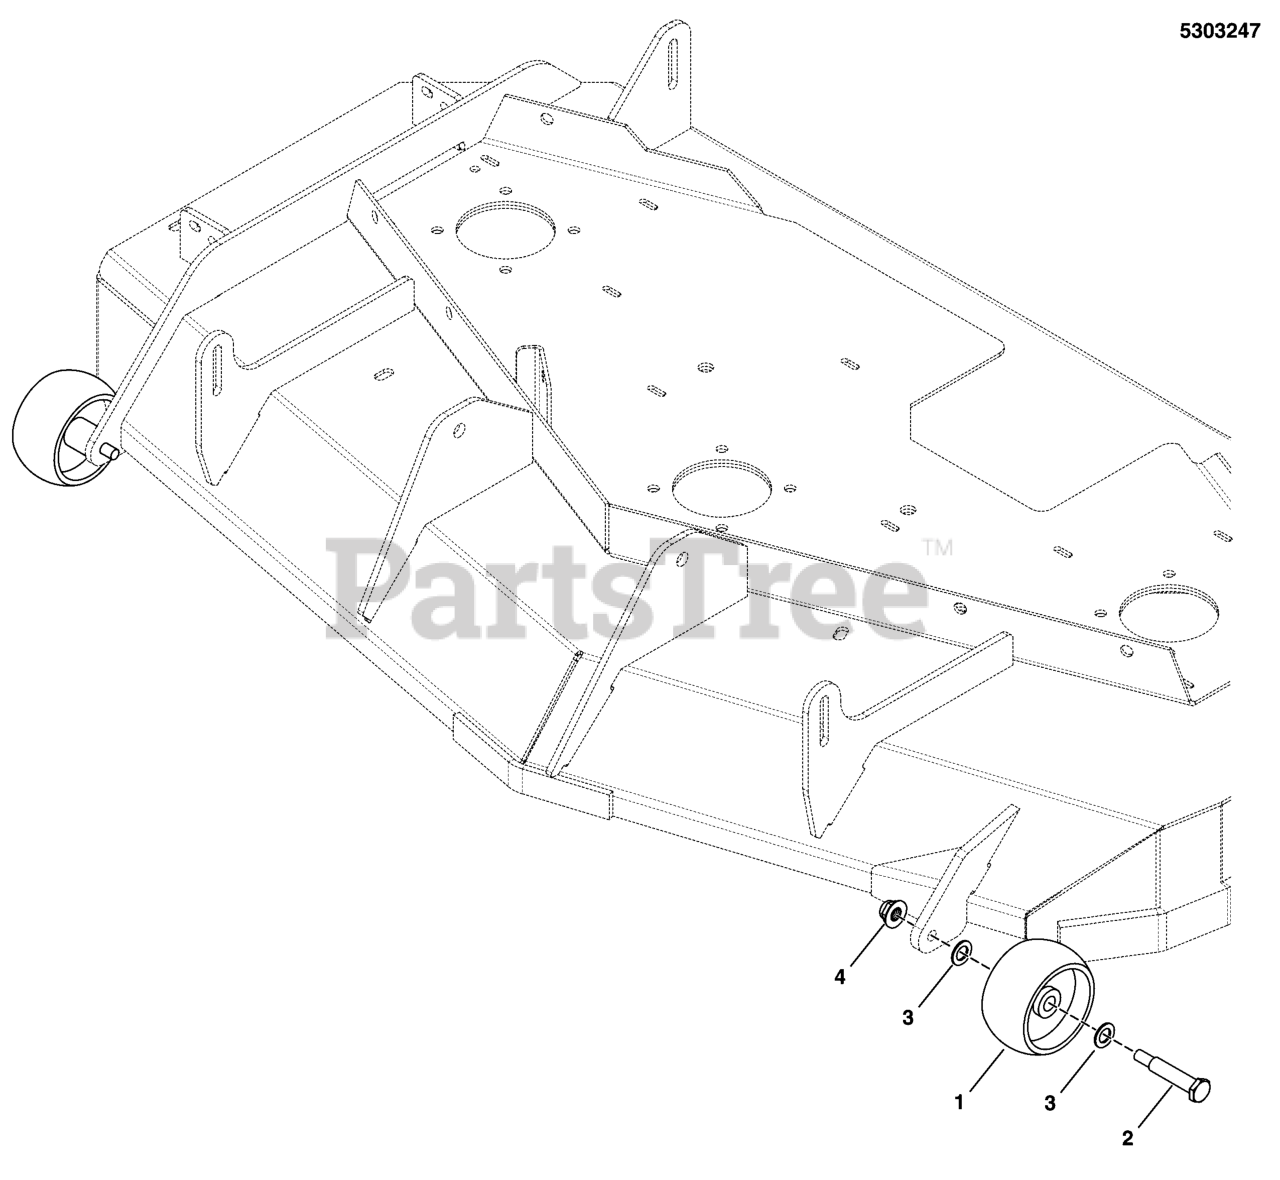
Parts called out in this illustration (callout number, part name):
1	WHEEL- 2.00 WIDE 3.88 DIA 0.531ID POLY
2	BOLT-WHEEL 3/8-16X2.781 .750 THRD
3	WASHER,.516IDX.875ODX.06,FLAT,ZC/CL
4	NUT, 3/8-16 HEX SIDE LOCK
